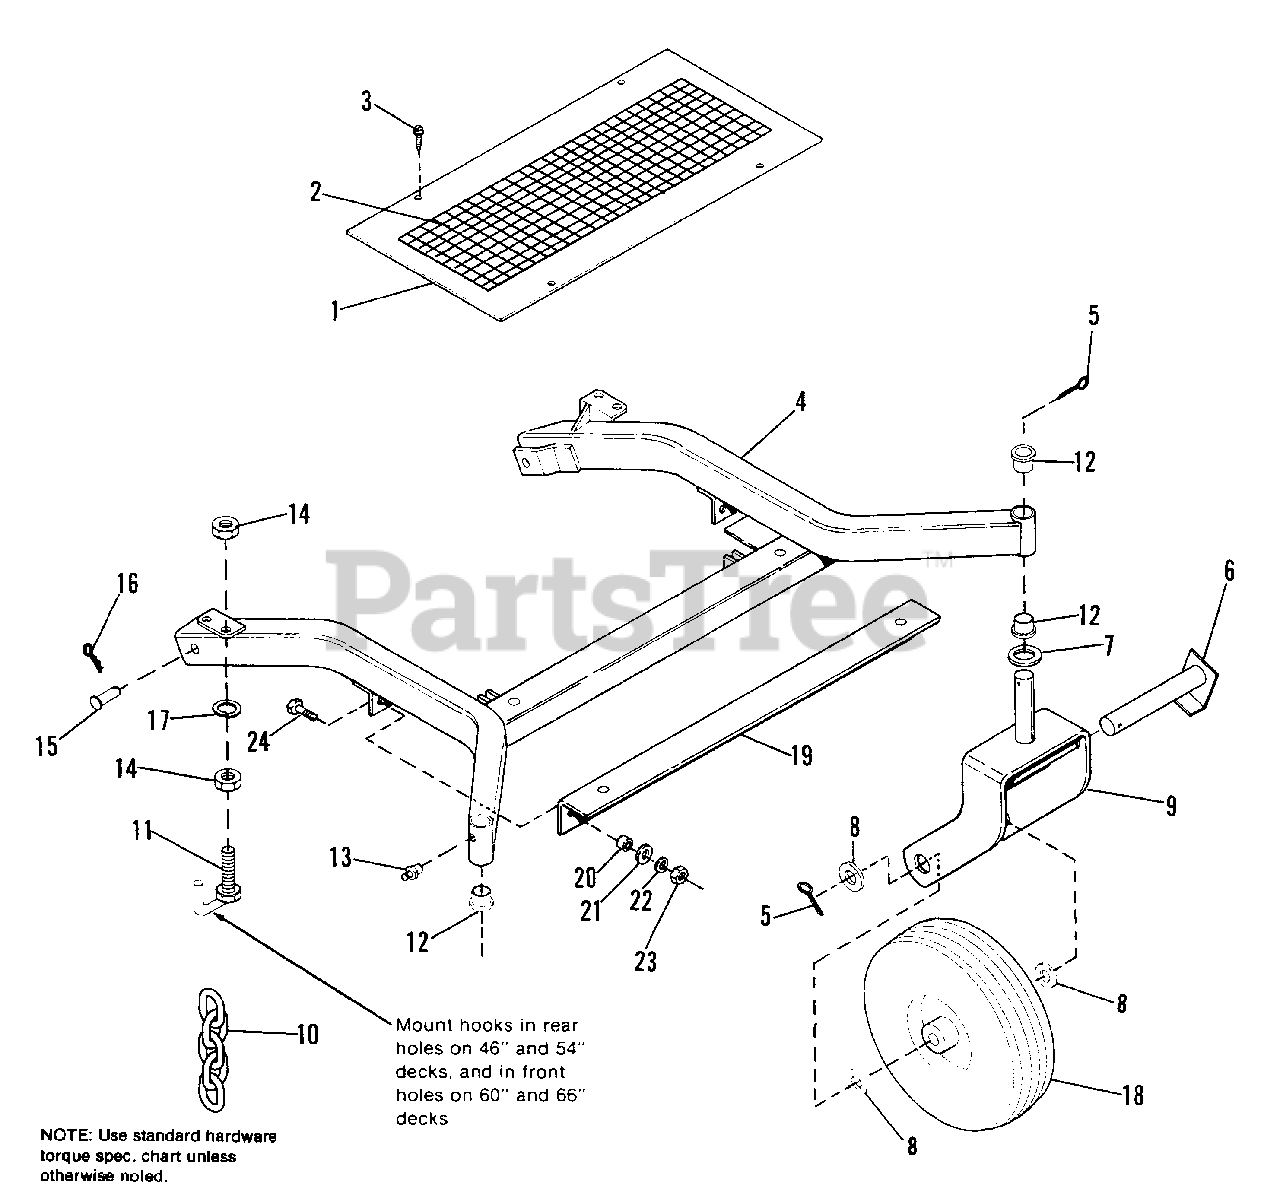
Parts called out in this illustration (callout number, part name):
1	COVER, 46" Mower
1	COVER, 54" Mower
1	COVER, 60" & 66" Mower
2	PAD, Non-Skid
3	SCREW, Taptite, 5/16-18 x 1/2
4	MOWER FRAME ASSY., 46" Mower
4	MOWER FRAME ASSY., 54" Mower
4	MOWER FRAME ASSY., 60" Mower
4	MOWER FRAME ASSY., 66" Mower
5	COTTER PIN
6	AXLE ASSY.
7	WASHER, Plain
8	WASHER, Plain
9	CASTER ASSY.
10	CHAIN, Lift
12	BEARING, Spindle
13	FITTING, Grease (Press Fit)
14	NUT, Hex, 1/2-13
15	CLEVIS PIN
16	COTTER HAIRPIN
17	LOCKWASHER, Spring, 1/2
18	TIRE ASSY., 4.10/3.50 x 4
19	BRACKET, Support
21	WASHER, Flat
22	LOCKWASHER, Spring
23	NUT, Hex, 3/8-16
24	CAPSCREW, Hex, 3/8-16 x 1-1/4"
